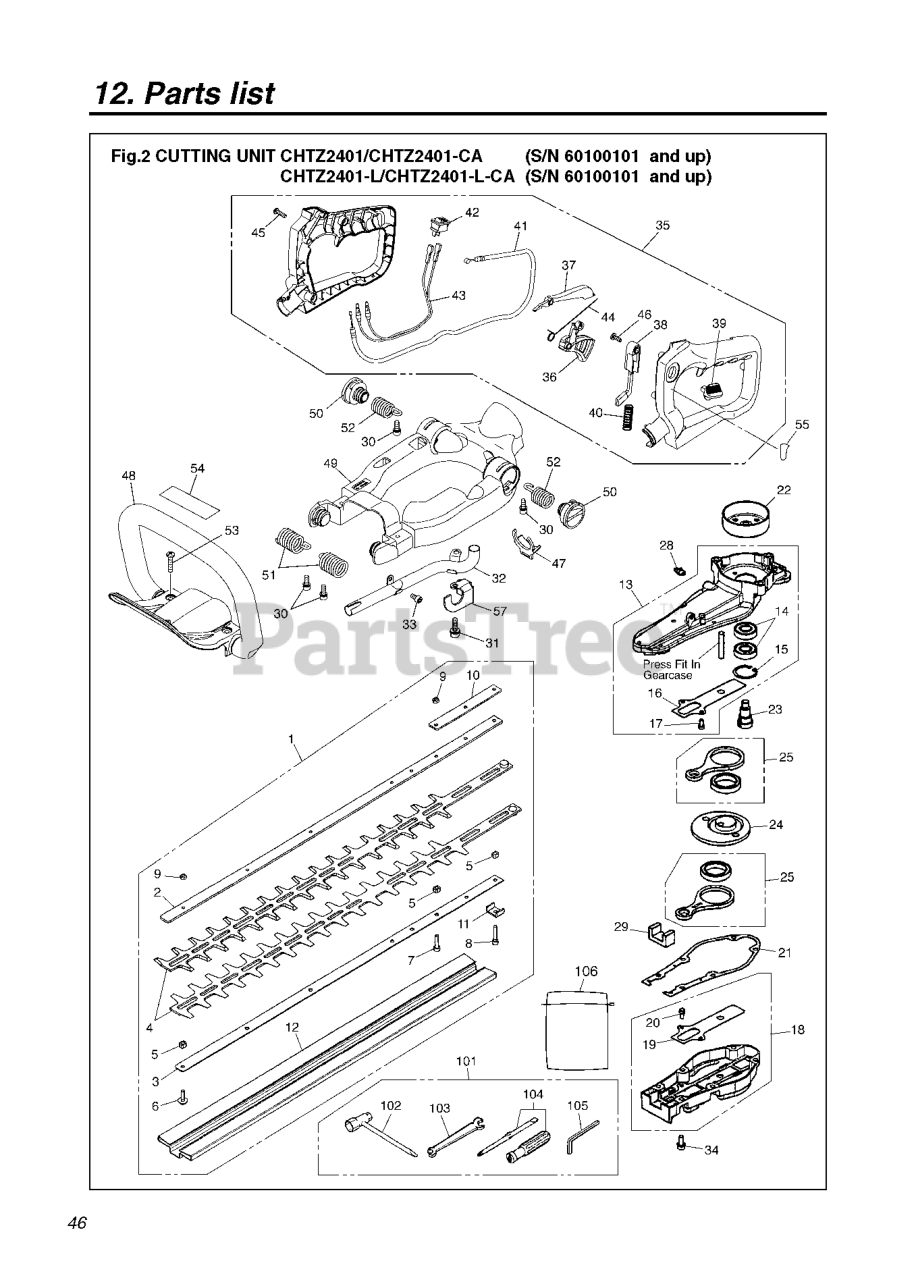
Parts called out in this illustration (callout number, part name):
1	BLADE ASSY.(RPLS 848D4A6500)
2	PLATE UPPER
3	PLATE LOWER
4	BLADE
5	SPACER
6	SCREW
7	BOLT
12	COVER
13	GEARCASE COMPLETE UPPER
18	GEARCASE COMP. BOTTOM
23	GEAR DRIVE
24	GEAR DRIVE
25	ROD ASSY
32	PIPE-EXHAUST
33	BOLT M5 X L10 ALLEN BOLT
35	HANDLE-REAR-A
36	LEVER.THROTTLE
38	LEVER
41	CABLE COMP
44	SPRING
46	SCREW
48	HANDLE F
51	SPRING F
52	SPRING R
57	BRACKET
101	TOOL-SET
